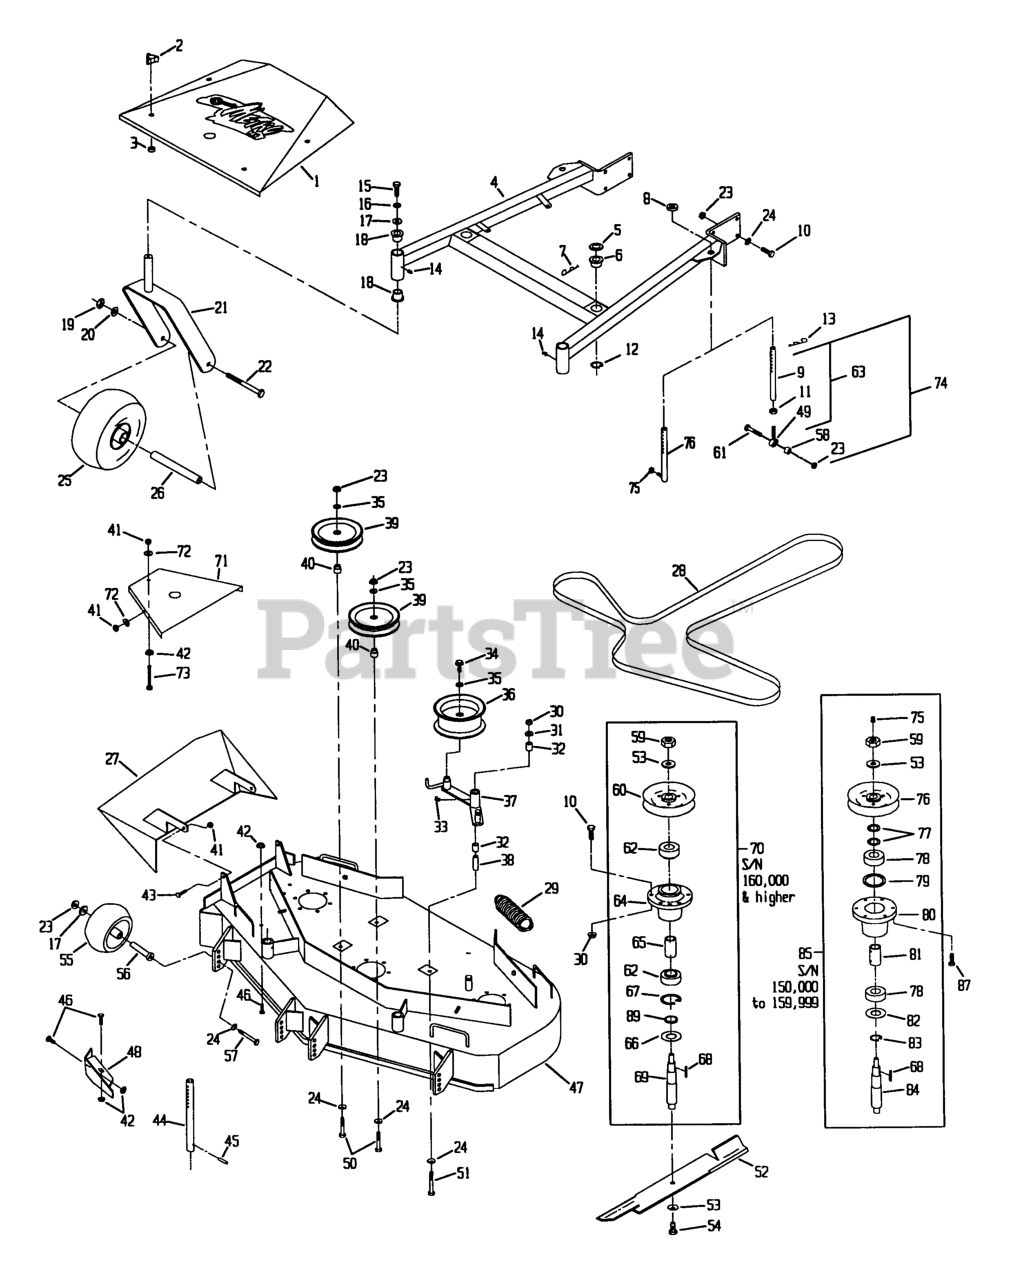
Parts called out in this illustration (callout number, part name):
1	SHIELD W/DECAL,MHP48
2	KNOB-3 PRONG
4	DECK SUPPORT W/BSHGS 48"
5	SPACER-DECK SUPPORT
6	BUSHING-DECK
9	LINK, DECK SUPPORT
13	PIN,HAIR COTTER
18	BEARING-FLANGED
28	BELT - V, B
32	SLEEVE-BEARING
38	BUSHING-PIVOT, IDLER
39	PULLEY-IDLER
40	BUSHING-IDLER
44	ROD,DECK SUPPORT
47	ASM,DECK W/DECALS TTHP/MH
49	BALLJOINT
51	SCREW-HH
53	WASHER-SPRING
55	ROLLER-SCALP, ANTI
56	BUSHING-ROLLER
60	SHEAVE,W/HUB 5.72
62	BEARING
65	SPACER-BEARING
66	GUARD-BEARING, BOTTOM
68	KEY-RECTANGLE
69	SHAFT,SPINDLE
70	HOUSING,CUTTER COMPLETE
73	BOLT,TAP HH
76	Link
77	SHEAVE,W/HUB 5.72
78	WASHER-SPACER
79	BEARING,HD SPINDLE
80	O-RING
81	HOUSING,BEARING
82	SPACER,BEARING
83	SEAL,MECHANICAL DUST
84	RING,SNAP WLDS N5000-244
86	Housing, Cutter Assembly
87	SCRW,TPTTE HH
89	SPACER-PULLEY/BEARING
